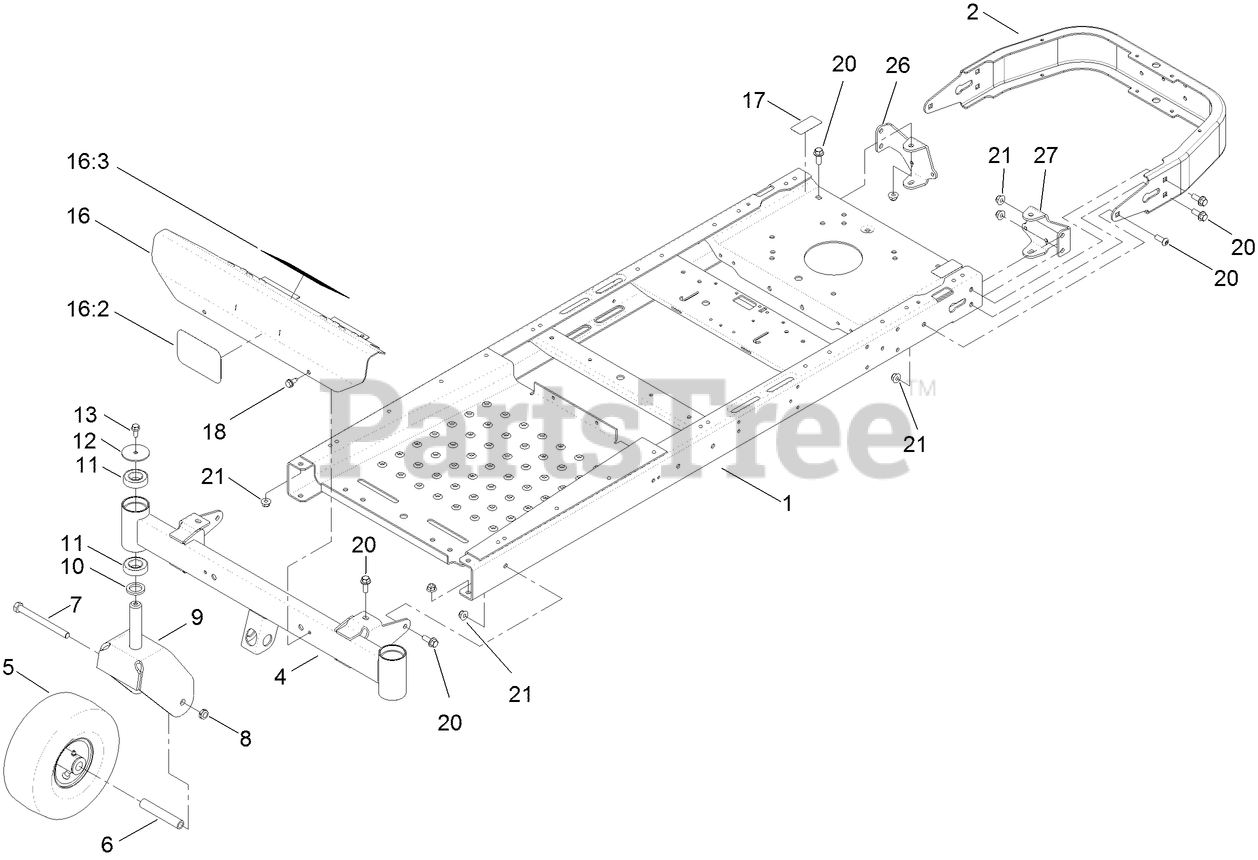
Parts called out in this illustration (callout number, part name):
2	BUMPER-REAR
4	AXLE-FRONT
5	CASTER WHEEL ASM (CST)
6	BUSHING-SPANNER
7	SCREW-HH
8	NUT-HEX
9	FORK-CASTER
10	WASHER-THRUST
11	BEARING-BALL
12	WASHER
13	SCREW-HHF
17	DECAL-BYPASS
18	SCREW-HWHTF
20	SCREW-HHF
21	NUT-HF, NI
26	MOUNT-HYDRO, REAR (RH)
27	MOUNT-HYDRO, REAR (LH)
